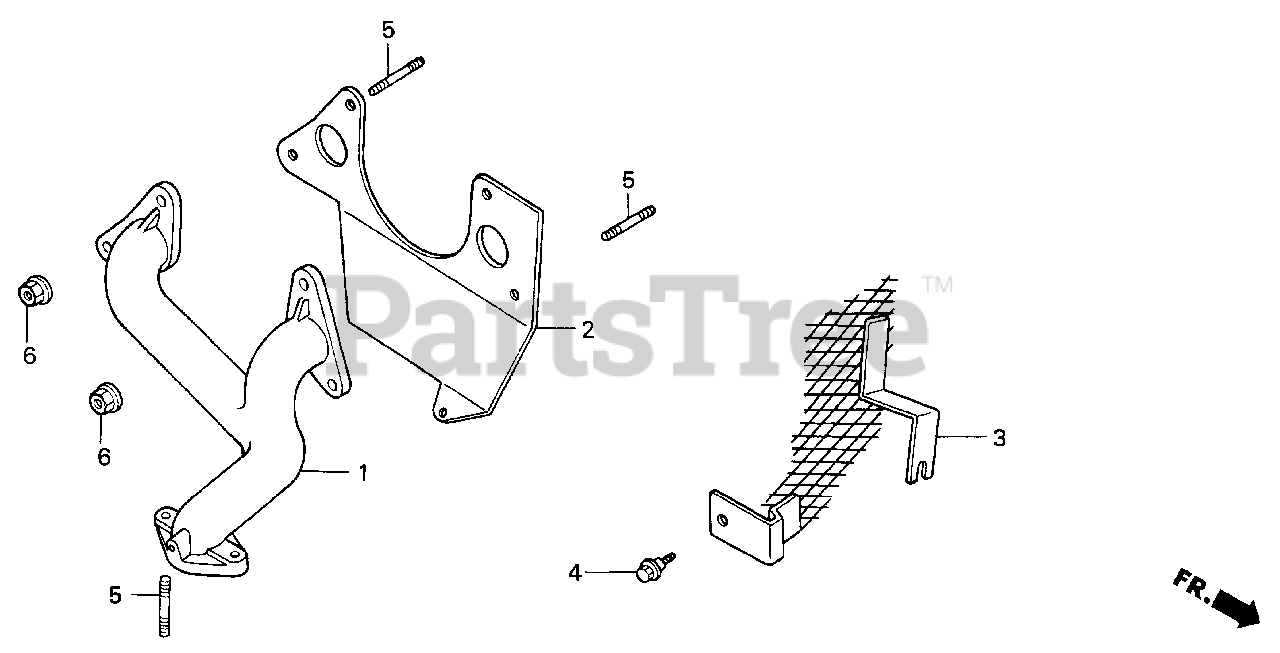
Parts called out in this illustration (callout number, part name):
1	MANIFOLD, EX.
2	GASKET, EX.
3	SCREEN, EX. COVER
4	BOLT, FLANGE (6MM)
5	BOLT, STUD (8X35)
6	NUT, FLANGE (8MM)
